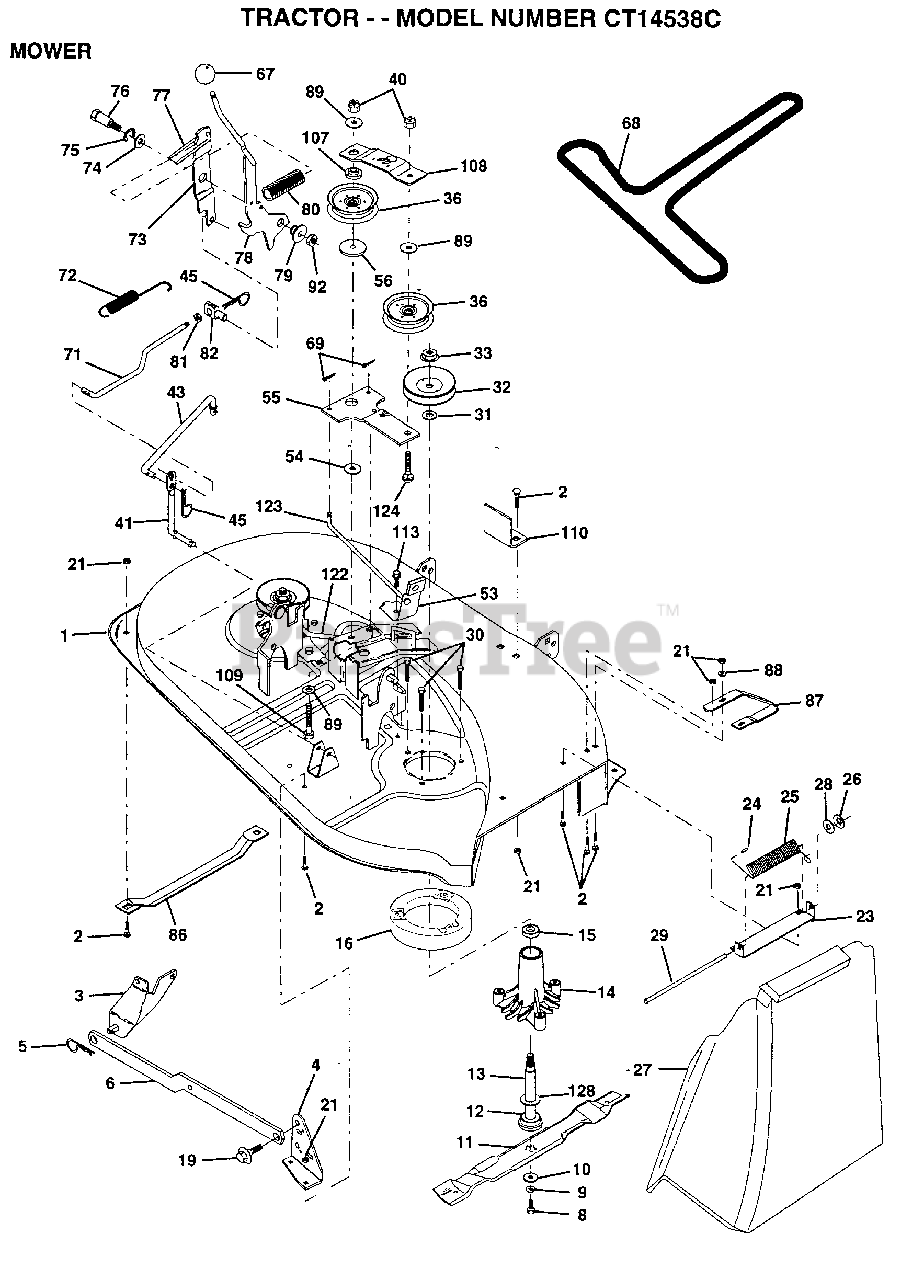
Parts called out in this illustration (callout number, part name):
2	BOLT
3	BRKT ASM SWAY BAR
4	BRKT DECK SW BAR
8	BLADE BOLT
10	WASHER.HARD.BLADE
11	"BLADE.38"" HIPERF"
12	BEARING.BALL
14	HSG ASM MANDREL
15	BEARING
16	STRIPPER RND MWR
19	BOLT SHD 5/16-18
23	BRKT DEFLECTOR
24	CAP-SLEEVE LT
25	SPRING TORSION
26	NUT PUSH M
27	DEFLECTOR-SHLD T
28	WASHER
29	ROD-HINGE T
31	WASHER
32	PULLEY.MANDREL.38
36	FLAT IDLER PULLEY
41	PIVOT ROD
43	CLUTCH ROD SECOND
45	RETAINER M
53	BRAKE ASM
54	HARDENED WASHER
55	IDLER ARM ASSY
56	SPACER RETAINER
67	KNOB T(3/8 HOLE)
68	BELT.V.T-PATH
71	ROD CLUTCH 38/42
72	RETURN SPRING
73	CLUTCH ARM SECOND
74	WASHER
75	RING
76	SHOULDER BOLT
77	SPRING KEEPER
79	BUSHING
80	SPRING.CLUTCH.MWR
81	NUT
82	TRUNION ADJ
86	RUNNER-LH M
87	RUNNER RH
88	WASHER M
89	WASHER GT
92	NUT
107	RETAINER SPACER
108	IDLER ARM STIFF
109	BOLT
110	UPSTOP DECK FT 38
113	SCREW
122	BRAKE ROD LH
123	BRAKE ROD RH
124	BOLT
128	WASHER.FELT.
